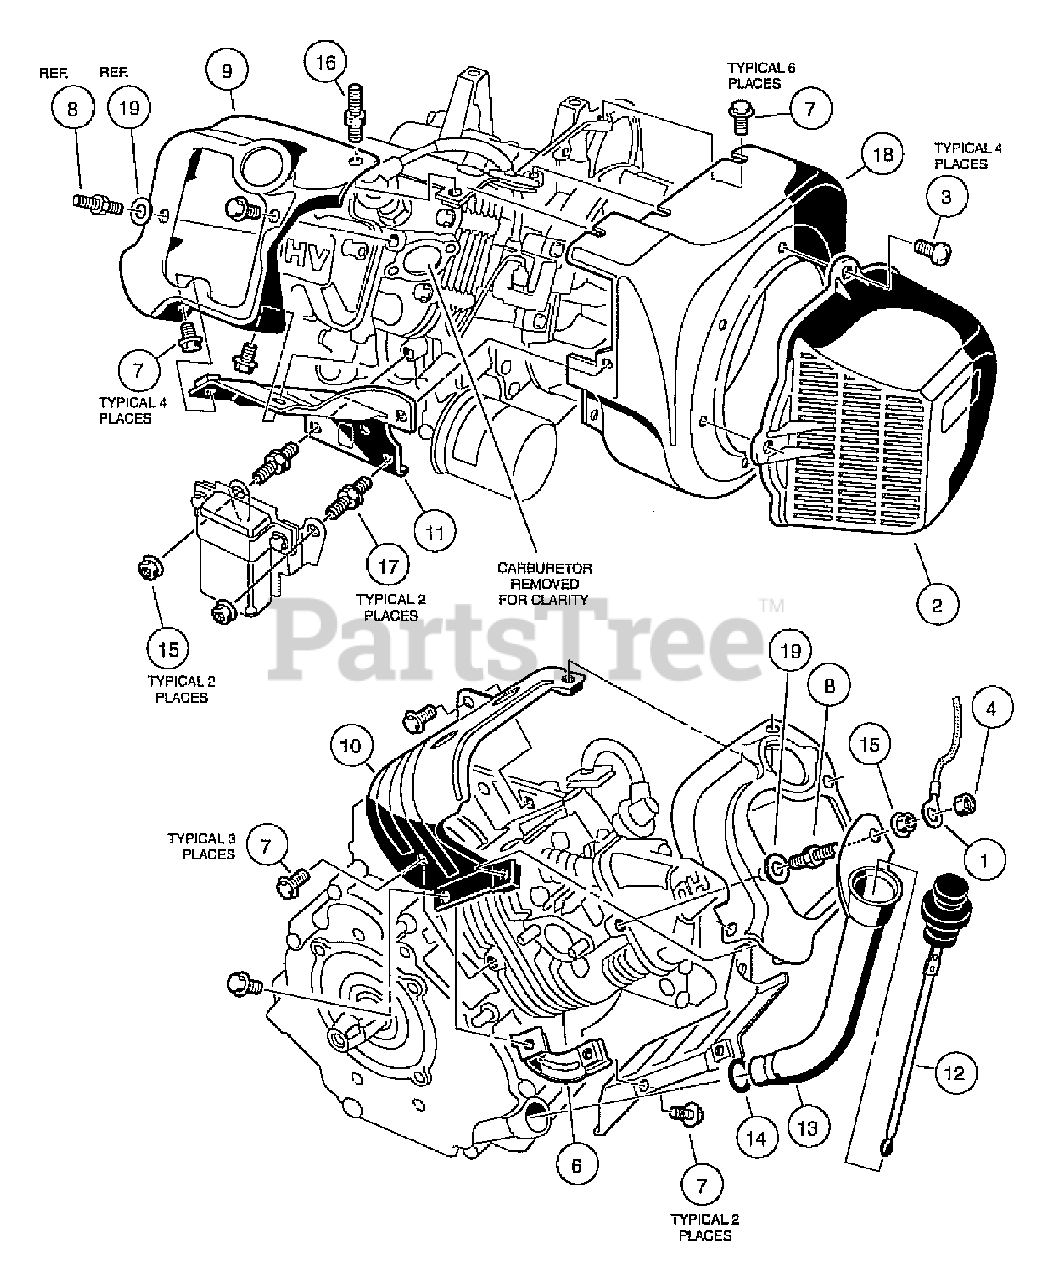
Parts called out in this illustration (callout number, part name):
1	Wire Assembly, #10, Uninsulated
2	Shroud, Fan
3	Screw, M6-1.00 X 10mm Pan Hd
4	Locknut, M6-1.00 Nylon Insert
5	Engine, FE290 (cw)
6	Bracket
7	Bolt, Flange Head, M6 x 1 x 12 mm
8	Bolt, Two-Ended
9	Shroud, Engine, FE290D
10	Shroud, Engine, FE290D
11	Shroud, Engine, FE290D
13	Tube, Oil Filler, FE290D
16	Screw, M6-1.00 Stud
17	Stud, M6-1.00, Two-Ended
18	Housing, FE290 Fan
19	Washer, 6 mm Flat
